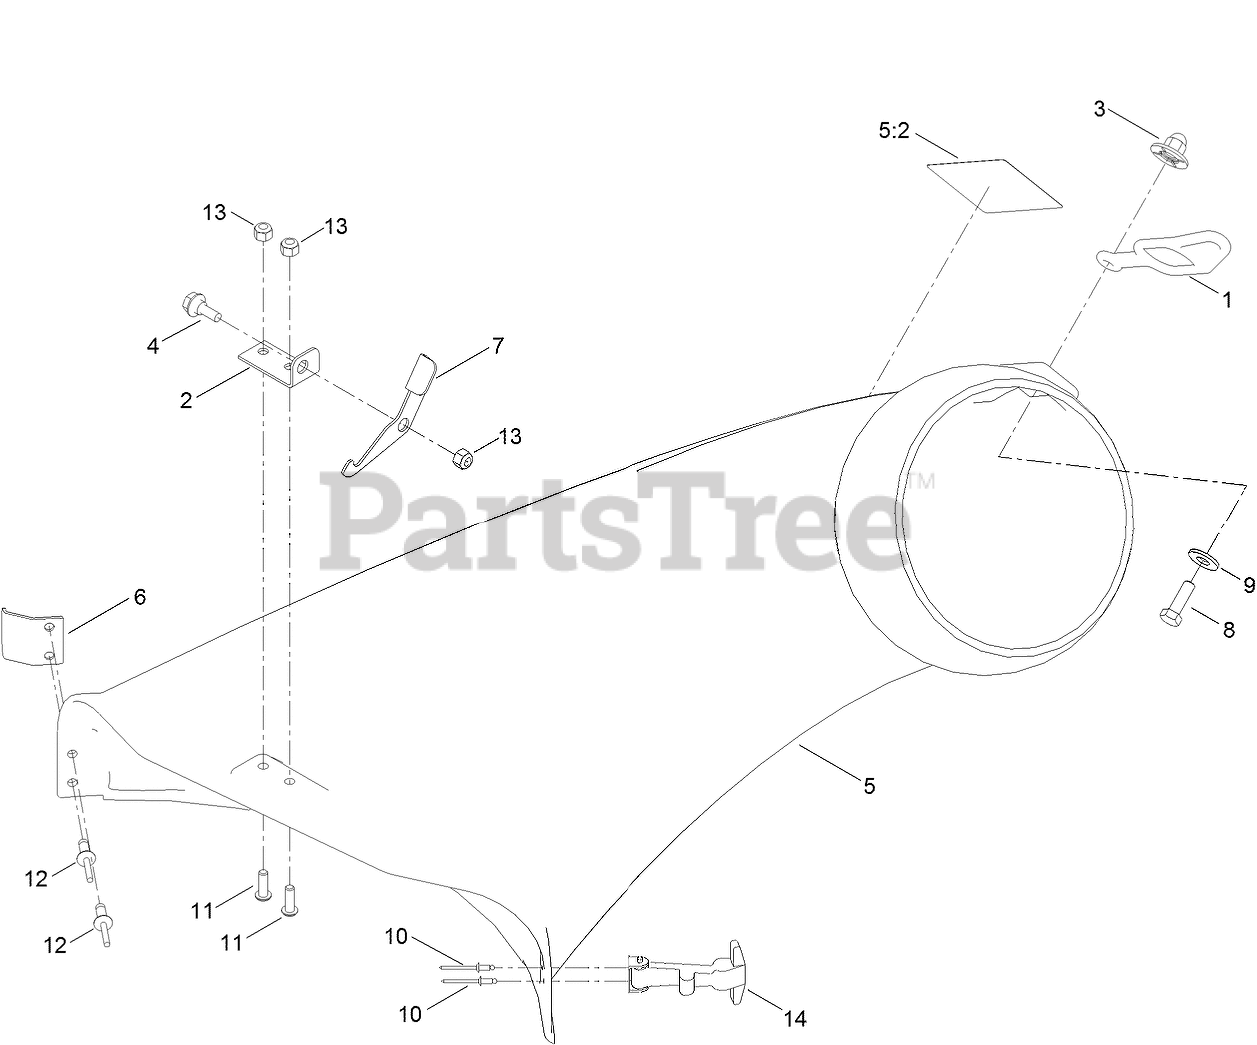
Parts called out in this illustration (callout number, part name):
1	RETAINER-DUCT
2	PLATE-PIVOT, CZ
3	NUT-IMPELLER
5	42 INCH BAGGER BOOT
5:2	DECAL-DANGER
6	BRACKET-ELBOW
8	SCREW-HH
9	WASHER-FLAT
10	RIVET-POP
11	SCREW-HSBH
12	RIVET-BLIND
13	NUT-HEX
14	HANDLE ASM
